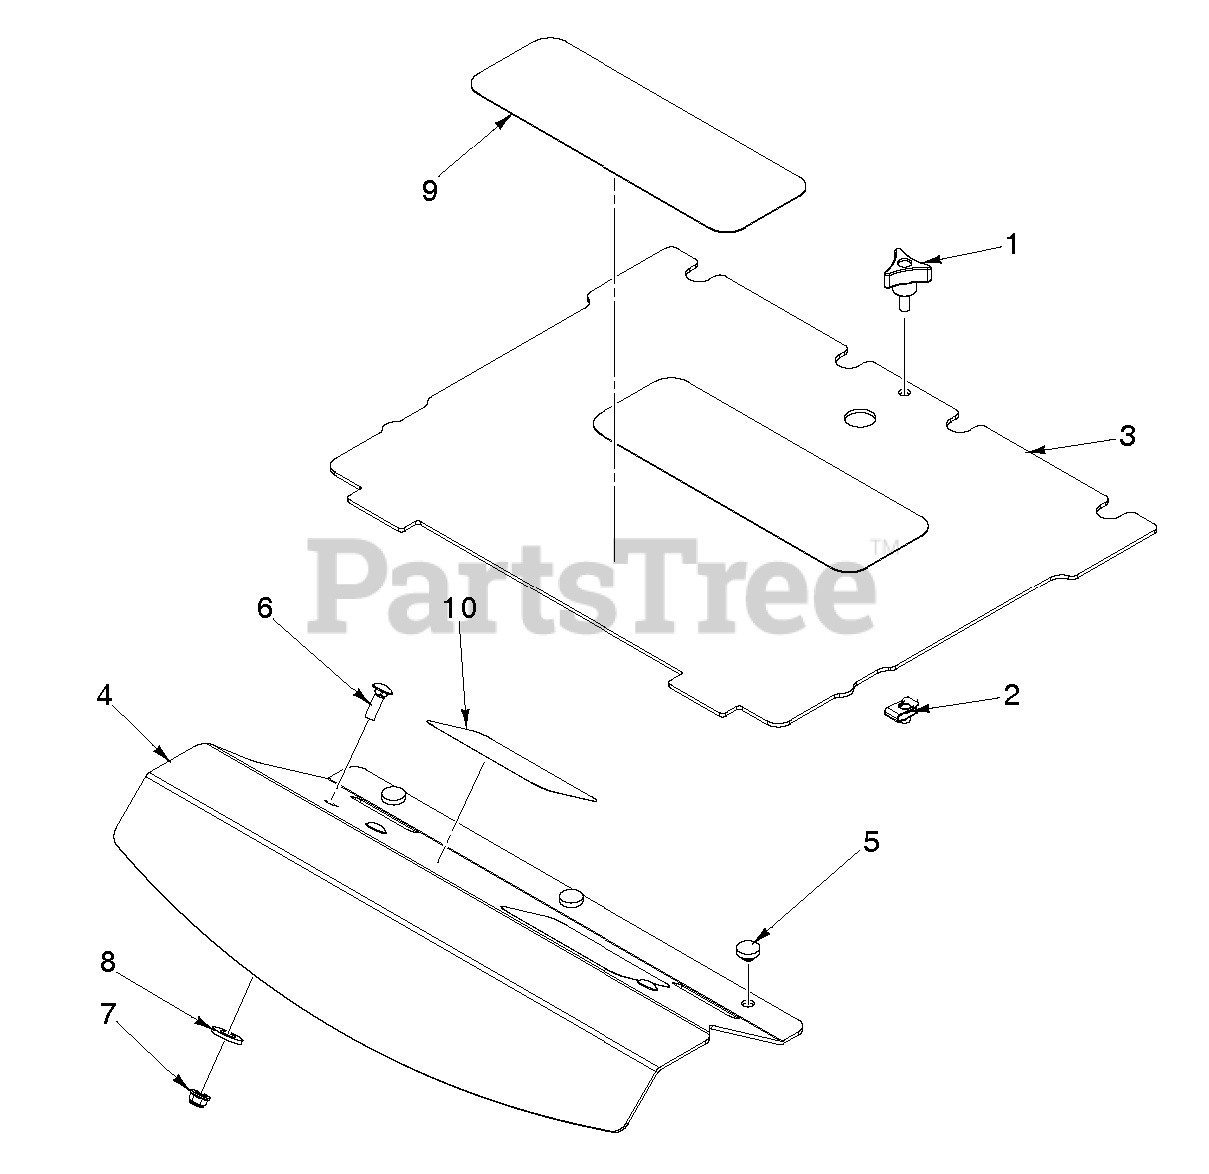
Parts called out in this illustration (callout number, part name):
1	GSPW Knobs
2	U-CLIP 5/16-18 NUT RETAINER
3	PLATE, FLOOR W/DECALS
4	PLATE FOOTREST ORANBE MS668
5	GROMMET, BUMPER
7	NUT HEXAGON FLANGE 5/16-18 ST
9	ANTI-SKID PAD
